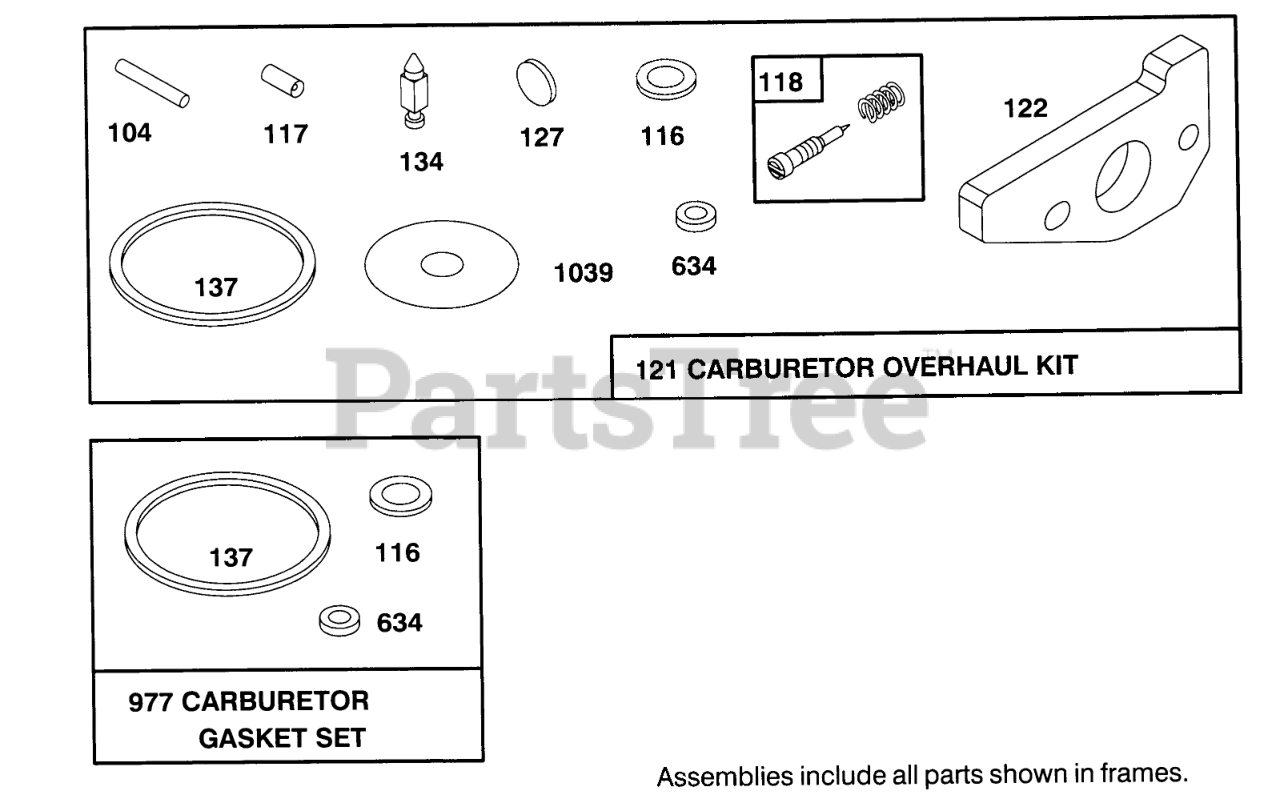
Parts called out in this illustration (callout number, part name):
104	FLOAT HINGE PIN
116	SEALING GASKET
118	VALVE KIT - NEEDLE
121	CARBURATOR OVERHAUL KIT
122	ADAPTER ASSEMBLY
134	Valve-Float (includes Seat)
137	FLOAT BOWL GASKET
634	SEAL WASHER
977	CARBURATOR GASKET SET
1039	FLOAT LIMITER
